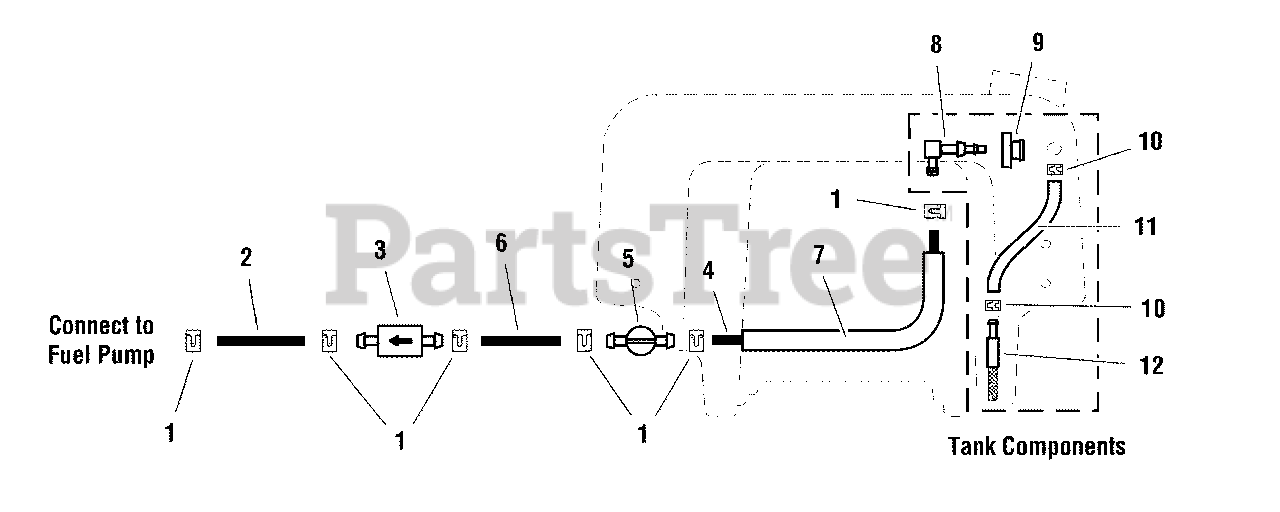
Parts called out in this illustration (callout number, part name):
1	CLAMP, Hose
2	HOSE, 5" (supplied with engine)
4	HOSE, 4"
5	VALVE, Fuel Shut-Off
7	WIRE LOOM, 1/2 ID 14" LONG
8	ELBOW FITTING
10	HOSE CLAMP
11	HOSE, 20"
12	SCREEN FITTING
